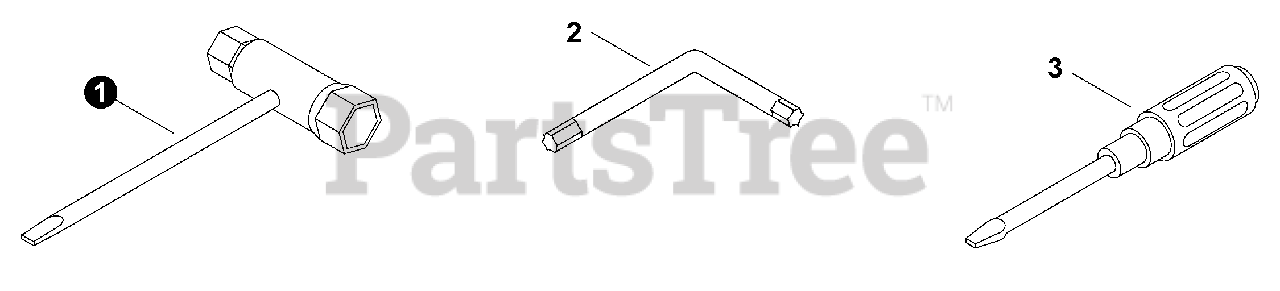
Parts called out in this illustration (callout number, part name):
1	T-WRENCH 13×19 L= 180
2	WRENCH, ALLEN
3	SCREWDRIVER 50MM
